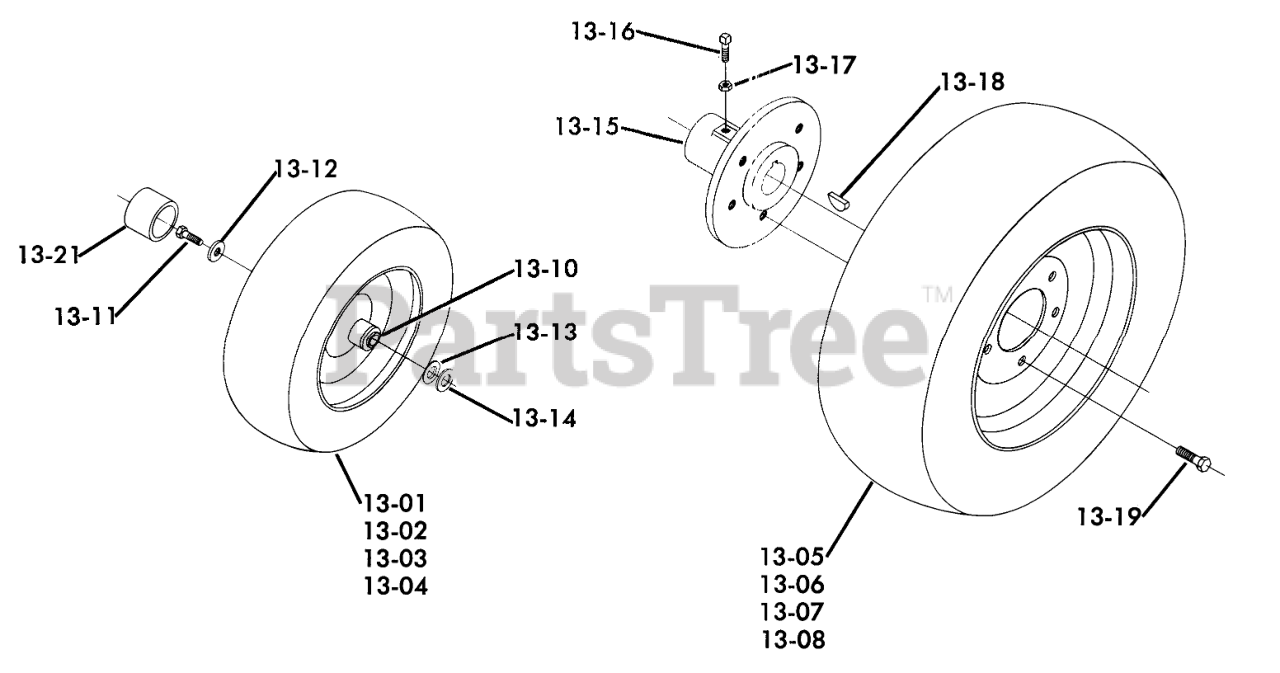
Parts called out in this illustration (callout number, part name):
13-01	Wheel-Complete
13-02	WHEEL
13-03	TIRE TURF SAVER 16X6.50-8
13-04	Tube
13-05	Wheel and Tire
13-05	Wheel & Tire Assembly
13-06	Wheel
13-07	Tire
13-07	Tire-Cleat, Rear
13-08	TUBE-INNER
13-09	VALVE
13-10	Bearing
13-11	Bolt
13-12	WASHER
13-13	WASHER
13-14	WASHER-SHIM
13-15	Hub Rear
13-16	Screw-Set
13-17	Nut
13-18	WOODRUFF KEY
13-19	Lug Nut
13-21	HUB CAP
